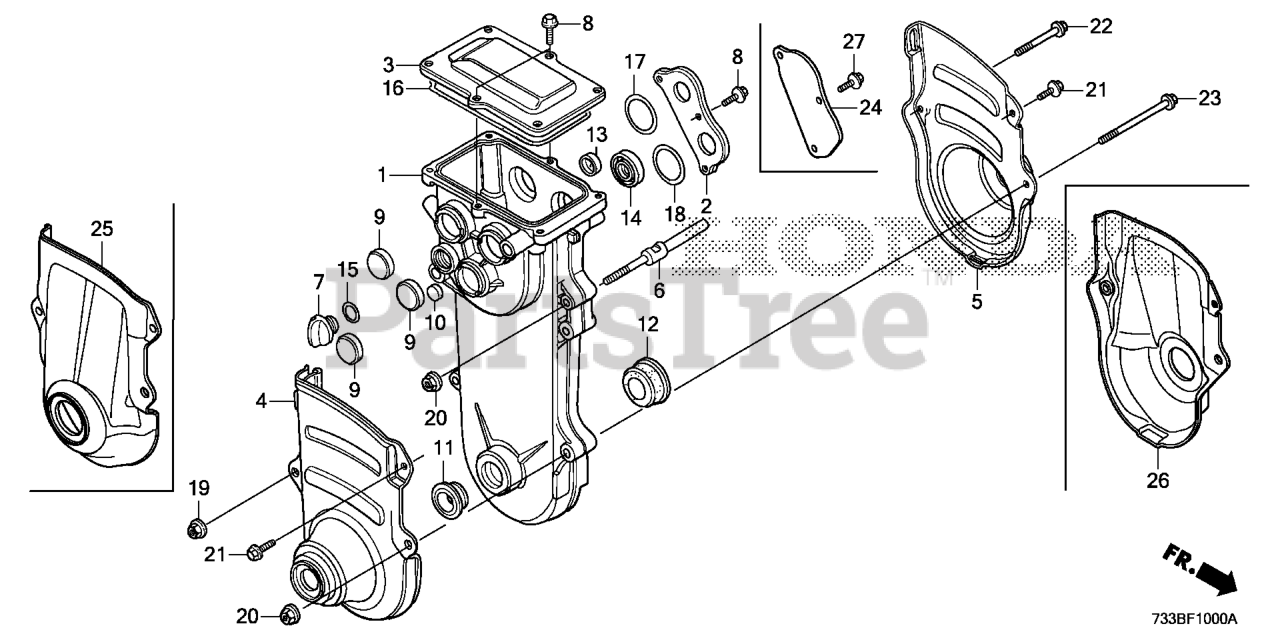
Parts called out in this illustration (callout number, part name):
1	CASE, TRANSMISSION
3	COVER, TRANSMISSION TOP
6	SHAFT, TENSIONER ARM
8	BOLT, FLANGE (6X12) (CT200)
9	PLUG, SEALING (28) (ARAI)
10	PLUG, SEALING (16) (ARAI)
11	SEAL, WATER (32X52X10.5) (NOK)
12	SEAL, WATER (32X58X10.5) (NOK)
13	PLUG, SEAL (22X7)
14	OIL SEAL (15X35X7) (ARAI)
15	O-RING (16MM)
16	O-RING A, TRANSMISSION CASE
17	O-RING (47.5X2.5)
18	O-RING (47.5X2.5)
19	NUT, FLANGE (6MM)
20	NUT, FLANGE (8MM)
21	BOLT, FLANGE (6X10)
22	BOLT, FLANGE (6X40)
23	BOLT, FLANGE (8X55)
24	PLATE, BEARING HOLDER
25	PROTECTOR, R. CASE
26	PROTECTOR, L. CASE
27	BOLT, FLANGE (6X14)
